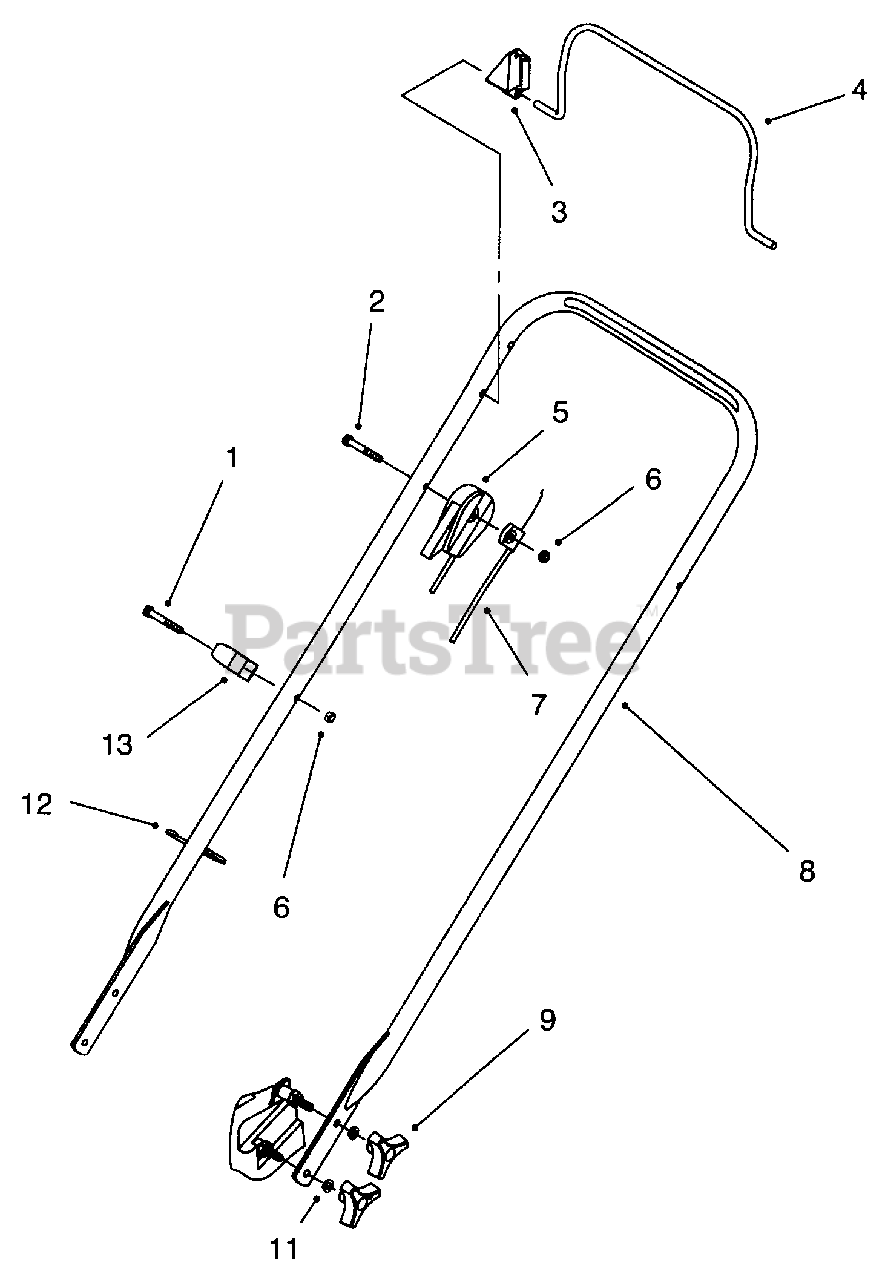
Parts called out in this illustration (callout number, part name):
1	Screw-Hex Hd. Cap
2	Screw-Hex Hd. Cap
3	Stop-Pivot
4	Bail-Flywheel Brake
5	Cable-Throttle
6	Nut-Lock
7	Cable-Flywheel Brake
9	Knob
11	Washer-Lock
12	Tie-Cable
13	Guide-Rope
